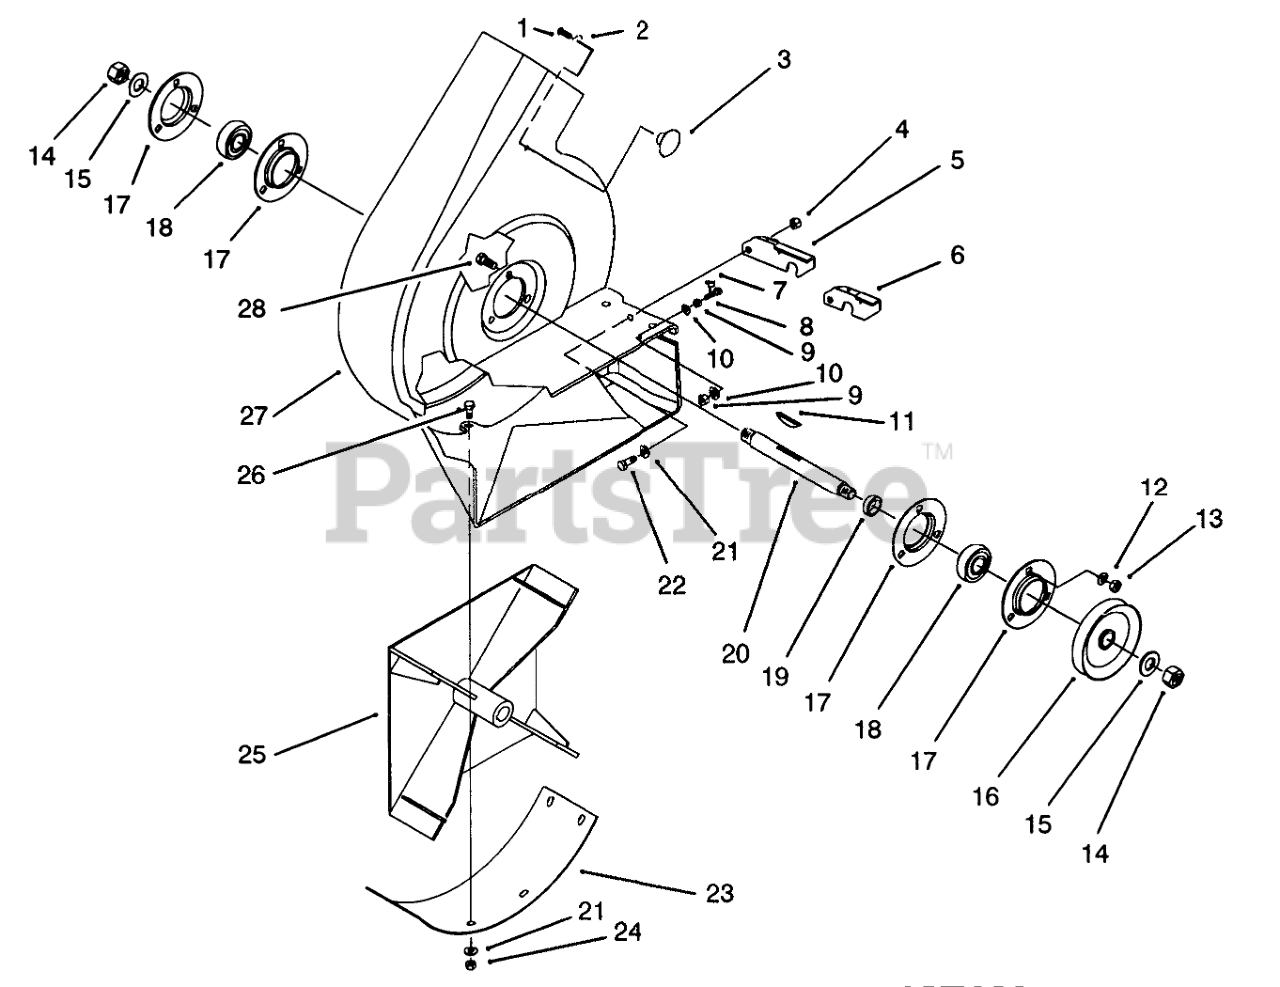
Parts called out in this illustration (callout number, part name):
1	SCREW-PPHTF
2	WASHER-PLAIN
4	NUT-LOCK, NI
5	48" BLOWER LATCH B
6	42" BLOWER LATCH B
7	SPRING-EXTENSION
8	SCREW-HWH
9	NUT-HEX
10	WASHER-FLAT
12	WASHER-LOCK
13	NUT-HEX
14	NUT-JAM
15	WASHER-LOCK
16	PULLEY-BLOWER
17	FLANGE
18	BEARING-BALL
19	Spacer
20	SHAFT-BLOWER
21	WASHER-FLAT
22	SCREW-HH
23	COVER-BLOWER, BOTTOM
24	NUT-LOCK, NI
25	Impeller
26	SCREW-CARRIAGE
27	HOUSING-VAC, BLOWER
28	BOLT-CARR
